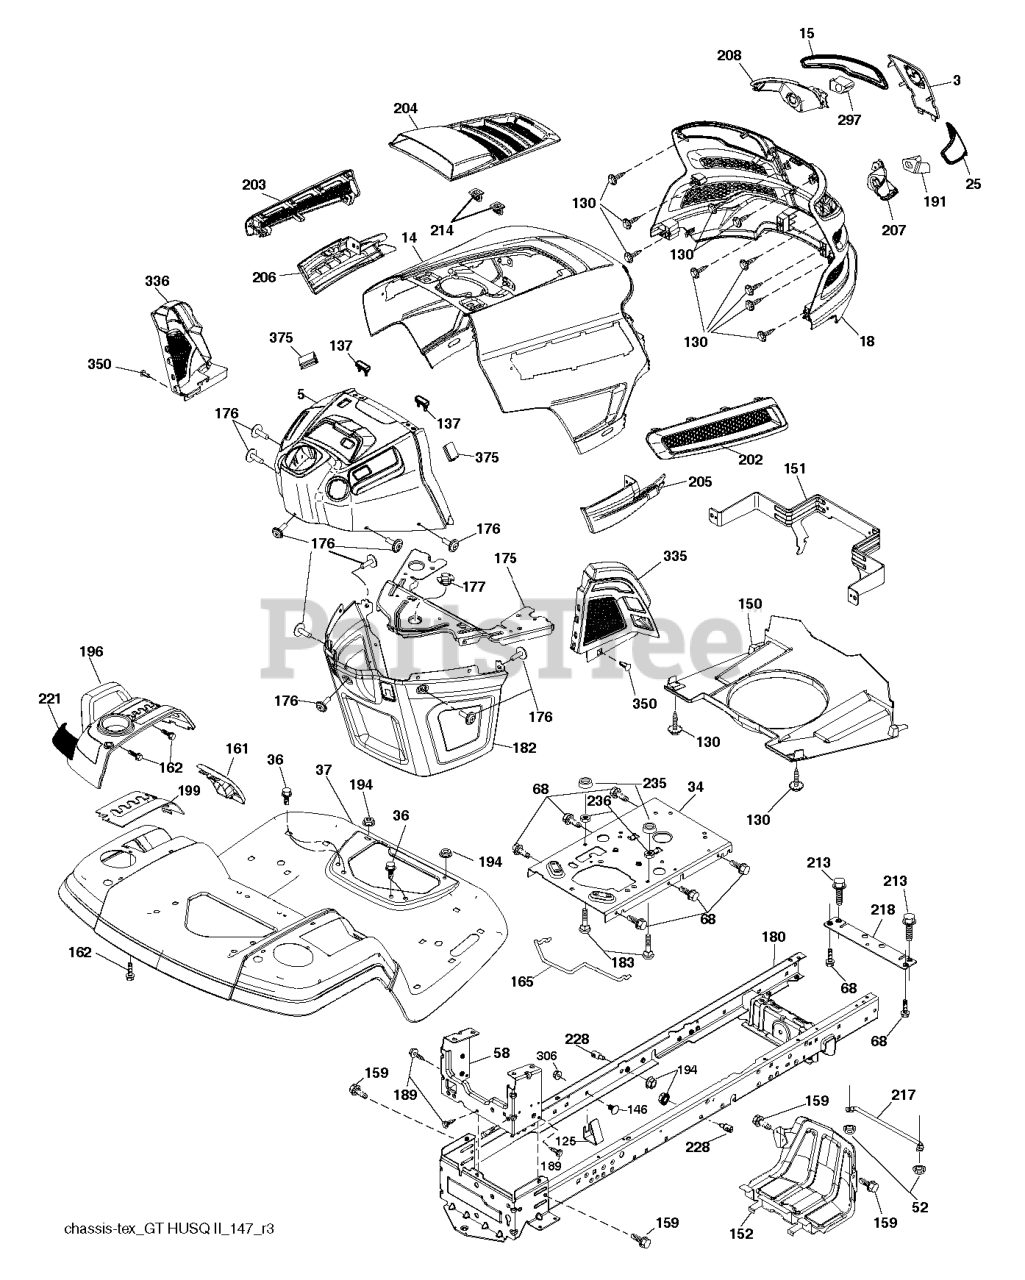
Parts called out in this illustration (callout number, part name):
3	APPLIQUE.SUBASM.GT.HUSQ.II
5	DASH.HUSQ2.SM.E.NC.HR.CHG.498
14	HOOD.ASM.HUSQVARNA.GT.TEX.ORAN
15	LENS.HEADLIGHT.LH.GTII.2011
18	GRILLE.SUBSTRATE.2011.
25	LENS.HEADLIGHT.RH.GTII.2011
34	PLATE.ENGINE.WELDED.CHASSIS
36	SCREW 5/16"
37	FENDER.PNT.TX.GT.CH/FW/DL.HUSQ
52	LOCKNUT
58	DRAWBAR.UPPER.2PC,LRG.FENDER
68	SCREW LT
125	CLIP.FUEL.LINE
130	SCREW.#10 X 0.750.BOS
137	BUMPER DASH
146	BOLT.RDHD.SHT.SQNK.3/8-16X5/8
150	AIR.DUCT.GTV.BLACK
151	BRACKET.PIVOT.HOOD.GT.HUSQ.II
152	SHIELD.BROWNING.PNT.GT.V2
159	SCREW, 3/8-16X3/4
161	CONSOLE.WINDOW.FUEL.HUSQ.GT
162	SCREW.HI-LO.CONSOLE
165	SUPPORT.TANK.REAR.W/TEX
175	PLATE.CROSSMEMBER.HUSQ
176	SCREW.#10-24X5/8.RN.QU
177	BUSHING, STEERING
178	CARGO.ASM.NET.TXGT.W/C
180	CHASS.WLDMNT.TLT.12GA/2PC.20"
182	DASH.LOWER.COMMON.12V.ADAPTOR
183	BOLT.5/16-18X1-1/4 FULL THD
189	SCREW
191	INSERT.REFLECTIVE.RH.HUSQ.GTII
194	NUT LOCK HEX FLANGE 5/16-18
196	CONSOLE.ASM.DECKLIFT.HUSQGT.DL
199	PLATE.DECK.LIFT.HUSQVARNA.GT
202	VENT.SIDE.RH.GT.HUSQ.II.
203	VENT.SIDE.LH.GT.HUSQ.II.498
204	VENT.TOP.HUSQ.GT2
205	SIDE.TRIM.RH.GT.HUSQ.II
206	SIDE.TRIM.LH.GT.HUSQ.II.GRAY
207	BEZEL LIGHT.RH.GT.II.MYLAR
208	BEZEL LIGHT.LH.GT.II.MYLAR
213	BOLT
214	CLIP.RETAINER.TINNER.
217	ROD.PIVOT.HOOD
218	X-PIECE.HOOD.STOP.NON/
221	REFLECTOR.LH.TEX GT HU
228	STUD.FASTNER.W/ANTI-ROTATE
234	BUMPER.HOOD.TEX.HUSQVARNA
235	SPACER FENDER
236	NUT.CENTERLOCK.5/16-
297	INSERT.REFLECTIVE.LH.HUSQ.GTII
306	NUT LOCK FLG 3/8-16 UNC
335	COVER.LOWER.DASH.RH.BLACK
336	COVER-LH.LOWER.DASH.GT2.BLACK
350	CLIP.X-MAS.TREE
